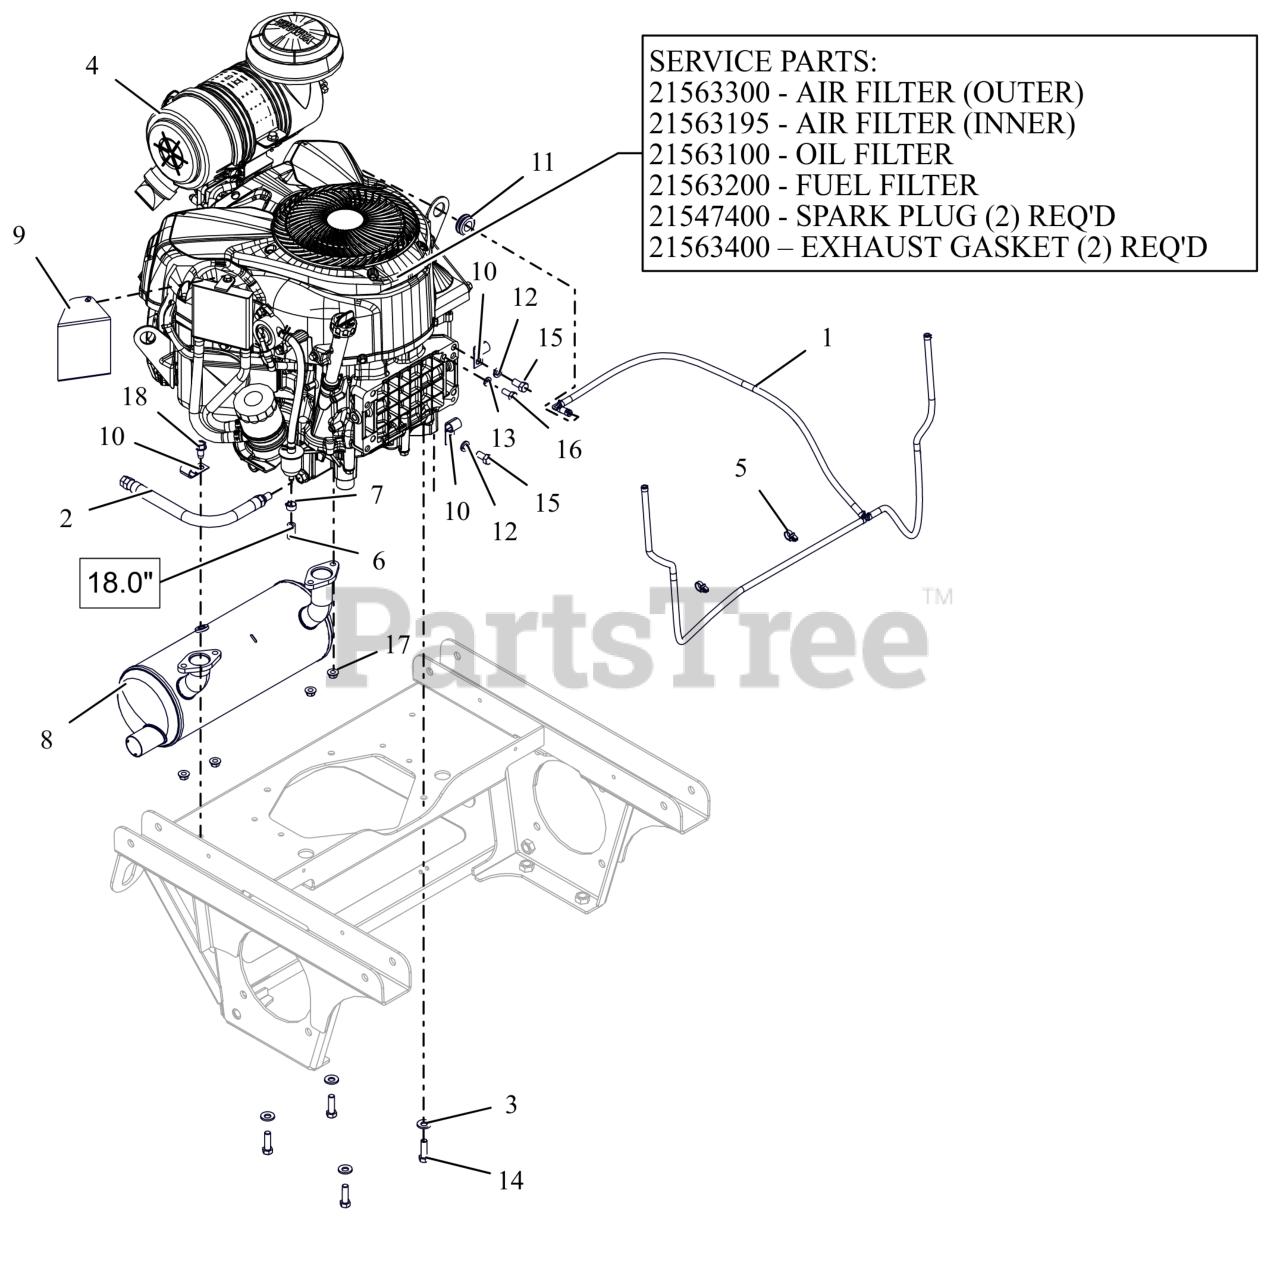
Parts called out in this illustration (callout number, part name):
1	ASM, VAPOR LINE
2	HOSE, OIL DRAIN
3	WASHER, 3/8" SPRING DISC
4	ENGINE, YAMAHA MX 825V
4	AIR FILTER (OUTER) - YAMAHA
4	AIR FILTER (INNER) - YAMAHA
4	FILTER, OIL - YAMAHA 824
4	FILTER-FUEL YAMAHA 824
4	PLUG, SPARK
4	GASKET, MUFFLER YAMAHA 824
5	ROUTING CLIP (1/2" ID)
6	HOSE, .25 LOW-PERM BULK GAS
7	CLAMP, FUEL LINE
8	MUFFLER, YAMAHA
9	DEFLECTOR,YAMAH OIL COOLER AIR
11	GROMMET,RUBBER.688 IDX1.000 OD
12	WSHR,LK-REG .375X.094 ZCC
13	WSHR,LK-REG .312X.078 ZCC
14	BLT, HEX .38-16X1.25 G5 ZCC NT
15	BLT,HEX .38-16X.75 G5 ZCC
16	BLT,HEX .31-18X.75 G5 ZCC
17	NUT-LK-TOP-FLG M8 ZCC
18	SCR,TAP .375-16X.75 HWH TR ZCC
